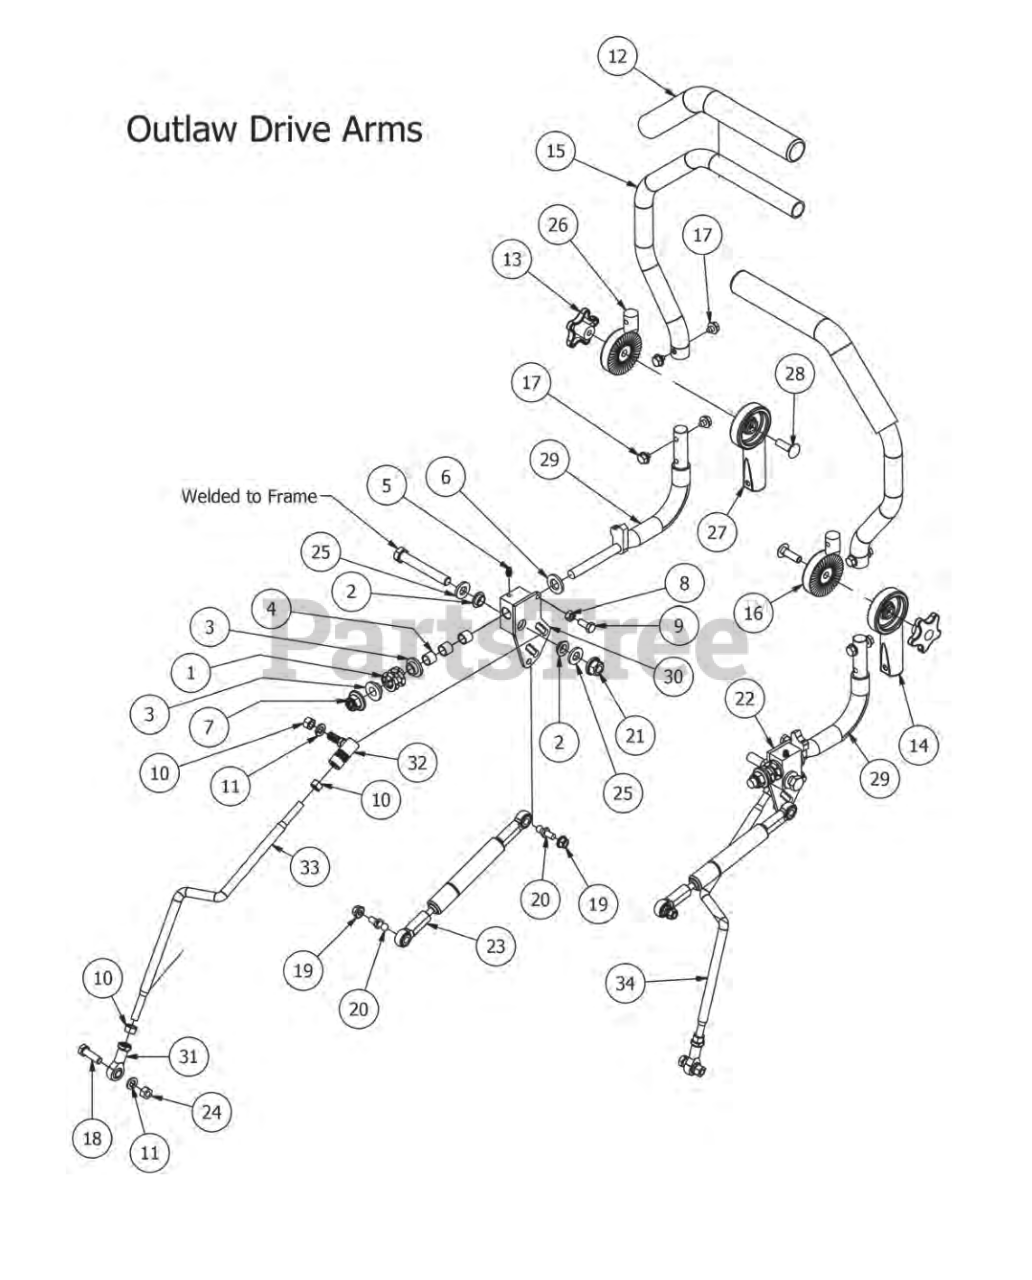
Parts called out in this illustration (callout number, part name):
1	Drive Lever Spring
2	Bushing for 2012 Drive Arms
3	.515 ID Nylon Shoulder Washer
4	.507 ID Nylon Bushing
5	1/4" Press in Grease Fitting
6	.635 ID Plastic Washer
7	1/2-13 Nylon Flange Nut-Orange
9	5/16" x 3/4" Hex Bolt
10	3/8" Fine Threaded Jam Nut
11	3/8" Lock Washer
12	Black Steering Grip
13	Black Knob for Adjustable Steering Arm
14	Lower Adjuster-Steering Arm- Right
15	Upper Tube-Adjustable Steering
16	Upper Adjust Steering Arm- Right
17	5/16-18 1/2 HWH Bolt-Steering
18	3/8" x 1 1/4" Hex Bolt
19	5/16" Flange Nut
20	10mm Damper Ball Stud-Steering
21	1/2-13 Hex Flange (GR.G) ZC
22	2013 Drive Lever Housing (Right)
23	Steering Damper For Outlaw
24	3/8-16 Hex Nuts Zinc
25	505x1x.125 Oil Impregnated washer
26	Upper adjuster-Steering Arm- Left
27	Lower Adjuster - Steering Arm- Left
28	3/8" x 1 1/4" Carriage Bolt
29	Steering Arm Elbow - Right
30	2013 Drive Lever Housing (Left)
31	Spherical Rod End - Outlaw
32	Quick Release Ball Joint
33	2015 Outlaw Push Rod - Left
34	2015 Outlaw Push Rod - Right
